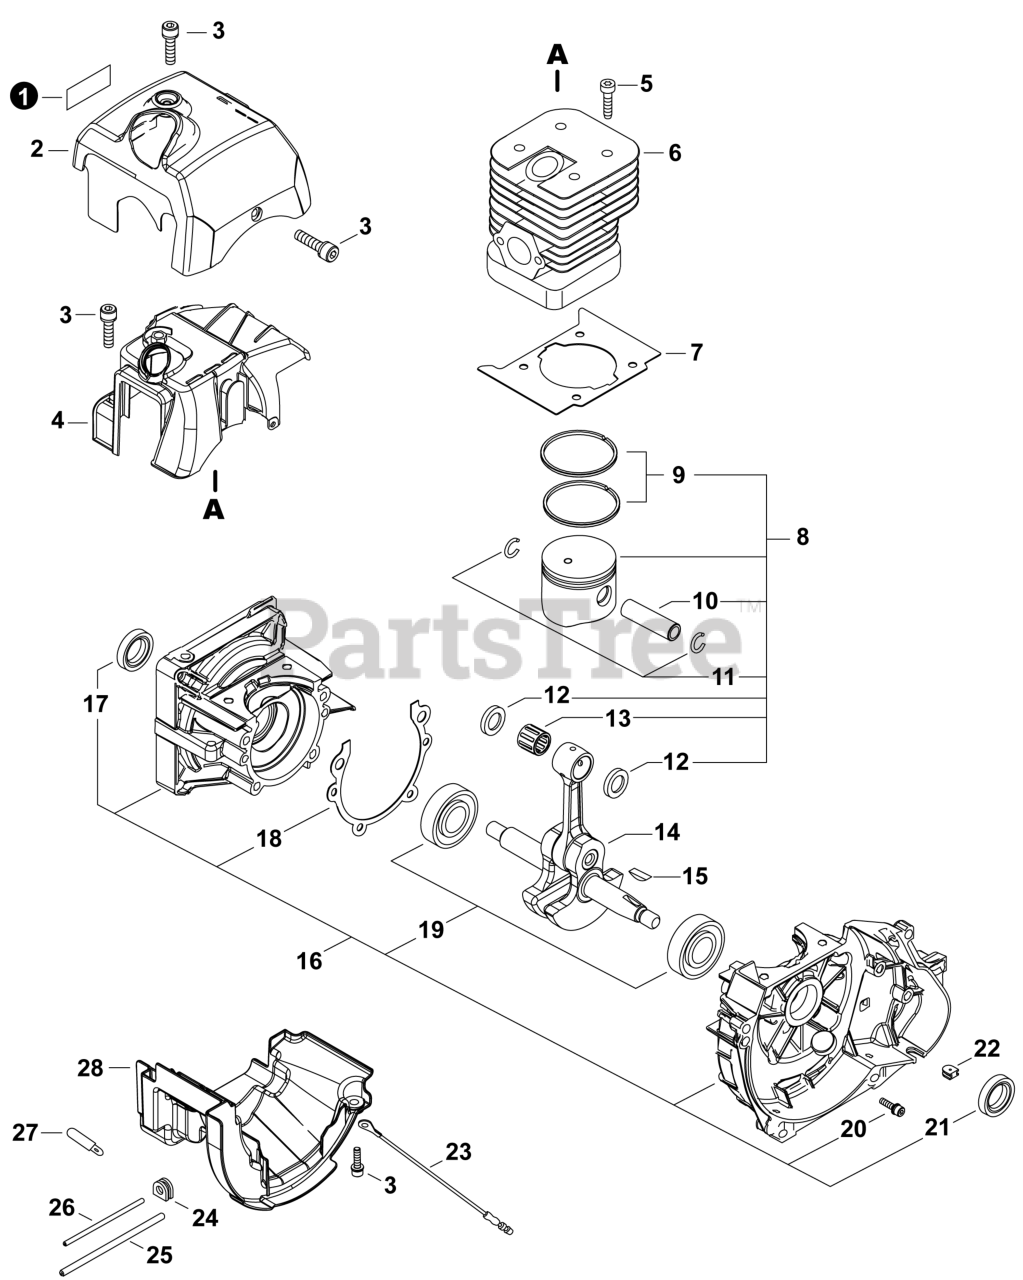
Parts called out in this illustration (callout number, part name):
1	LABEL - MODEL SRM-420ES
2	COVER, ENGINE
3	BOLT, TORX 5×16
4	COVER, CYLINDER
5	BOLT, TORX 5×20
6	CYLINDER
7	GASKET, CYLINDER
8	PISTON KIT
9	RING, PISTON
10	PIN, PISTON 10
11	RING, SNAP Ø10
12	WASHER, THRUST
13	BEARING, NEEDLE
14	CRANKSHAFT ASSY
15	KEY, WOODRUFF
16	CRANKCASE SET
17	SEAL, OIL 12
18	GASKET, CRANKCASE
19	BEARING, BALL 6201
20	BOLT, TORX 5×35
21	SEAL, OIL 12
25	TUBE, INSULATOR 8×9×111
26	PIPE, FUEL 3×6×165 BLACK
28	PLATE, INSULATOR
